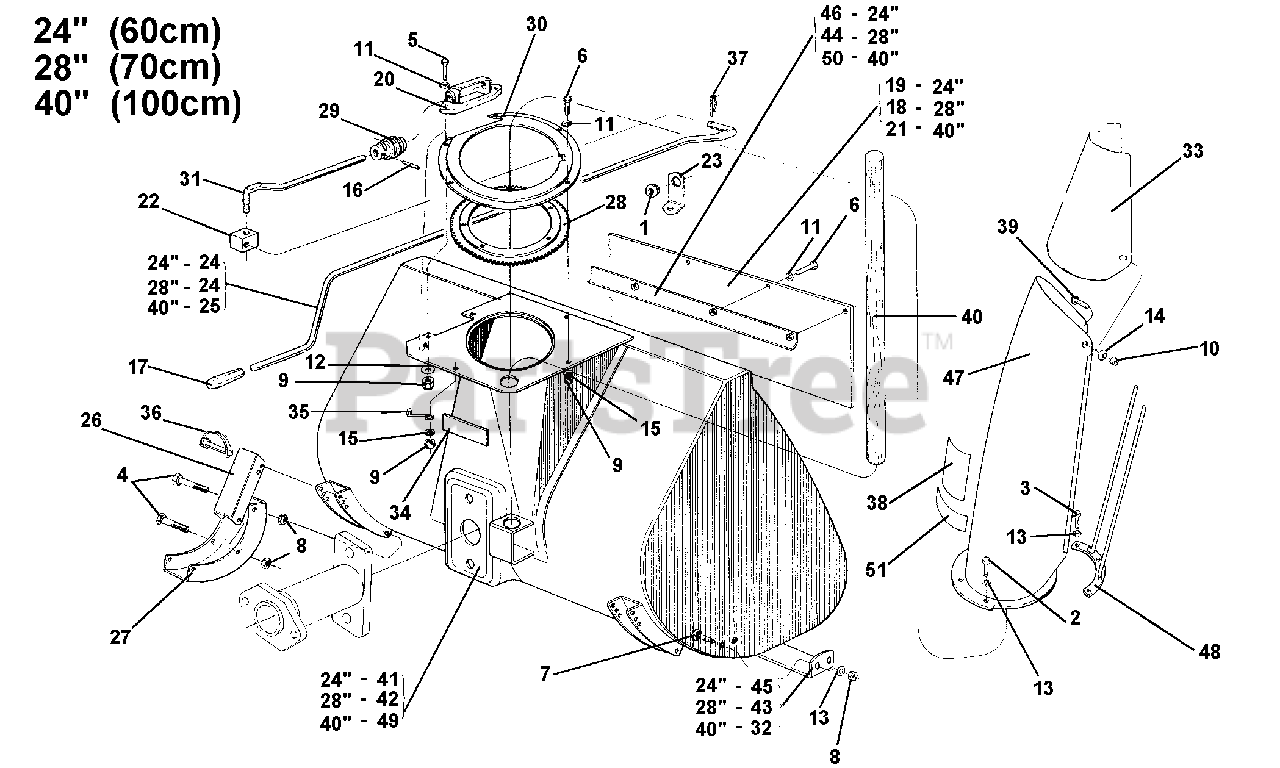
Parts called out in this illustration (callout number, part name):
2	SCREW TE M6 X 10 UNI 5739-5S
3	SCREW TE M6 X 14
4	SCREW TE M6 X 55
5	SCREW M6 X 25
6	SCREW TE M6 X 16
7	SCREW M6 X 16
8	NUT, SELF LOCKING M6
9	SELF LOCKING NUT M6
10	NUT, SELF LOCKING M10
11	WASHER, FLAT 6.4
12	FLAT WASHER
13	SUPER WASHER 6 DIN 6796
14	SUPER WASHER 10 DIN 6796
15	WASHER, LOCK 6.4
16	PIN, LOCKING SW 3 X 22 SPIRAL
18	MUDFLAP 70 CM
19	MUDFLAP 60 CM
20	SCREW SUPPORT
21	MUDFLAP 100 CM
24	FUNNEL CONTROL ROD
25	FUNNEL CONTROL ROD
31	ROD EXTENSION
32	BLADE 100 CM
35	GAS SHEATH SUPPORT
38	FUNNEL STICKER
39	SCREW M10 X 25
41	BLADE 70 CM
42	SNOW THROWER CRANKCASE 70 CM
43	BLADE 70 CM
44	SNOW THROWER CRANKCASE 60 CM
45	BLADE 60 CM
46	MUDFLAP STOP 60 CM
48	FUNNEL GRATE
49	SNOW THROWER CRANKCASE 100 CM
50	STOP 100 CM
51	STICKER "MADE IN ITALY"
